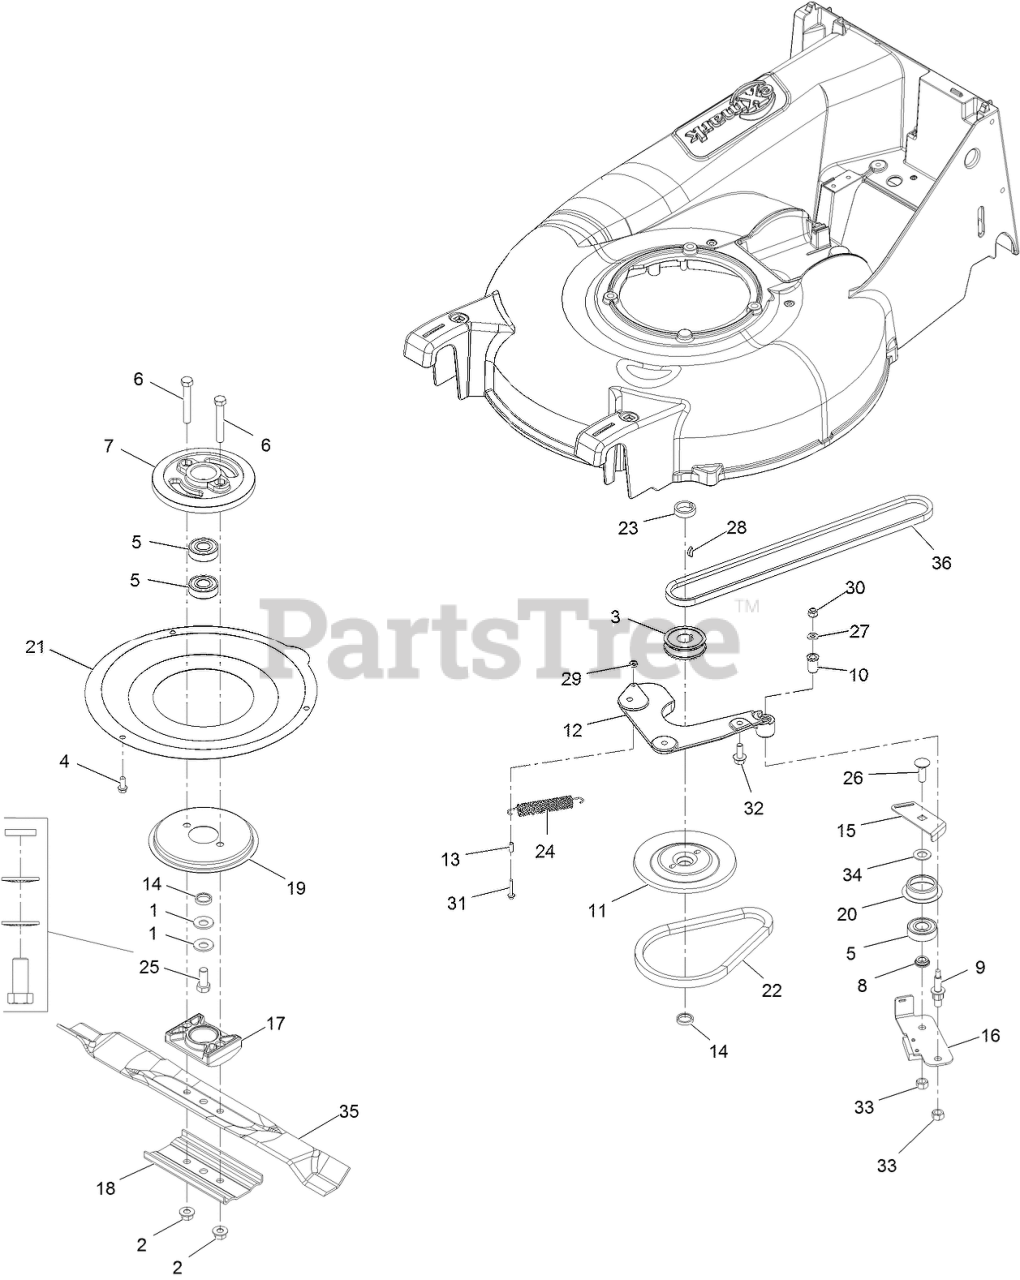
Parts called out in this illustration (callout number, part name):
1	WASHER-SPRING
2	NUT-FLANGE, LOCK
3	PULLEY-DRIVER
4	SCREW-HWH
5	BEARING-BALL
6	SCREW-HH
8	SPACER-BEARING
9	BOLT-SHOULDER
10	BUSHING
11	PULLEY-DRIVER, UPPER
12	PLATE-MOUNTING, BBC
13	SPACER-BBC
14	SPACER-PLATE, BBC
15	Plate-Guide
16	PLATE-BRAKE
17	SUPPORT-BLADE
18	SUPPORT-BLADE
20	RETAINER-BELT
21	COVER-BBC
22	BELT
23	SPACER-PULLEY
24	SPRING-EXTENSION
25	SCREW-HH
26	SCREW-CARR
27	WASHER-FLAT
28	KEY-WOODRUFF
29	NUT-LOCK, NI
30	NUT-LOCK, NI
31	SCREW-TAP
32	SCREW-HHF
33	NUT-HEX
34	SPACER
35	Blade - Medium Lift, 20.5
36	BELT,3L P21 DRIVE
